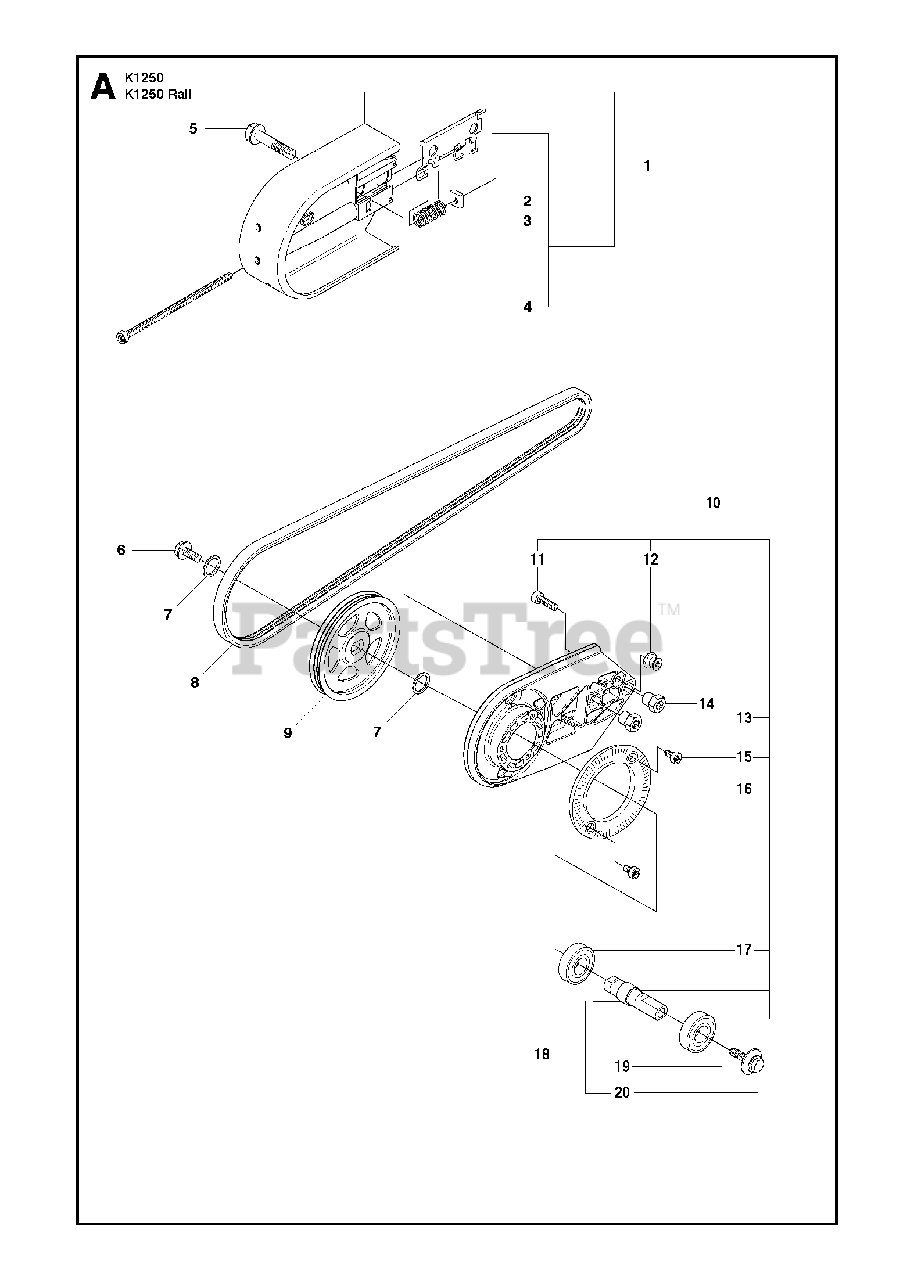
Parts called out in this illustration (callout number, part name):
1	BELT GUARDIncl. 2 - 4
1	BELT GUARD"Rail 14"", Incl. 2 - 4"
1	BELT GUARD"Rail 16"", Incl. 2 - 4"
3	COMPRESSION SPRING
8	BELT"14"", 16"", Rail 14"""
8	BELT"Rail 16"""
10	BEARING HOUSINGIncl. 11 - 13, 15 - 17
12	TORSION STOP
13	BEARING HOUSINGIncl. 14
15	SCREW IHSCFM
17	BALL BEARING
18	SHAFTIncl. 19-20
